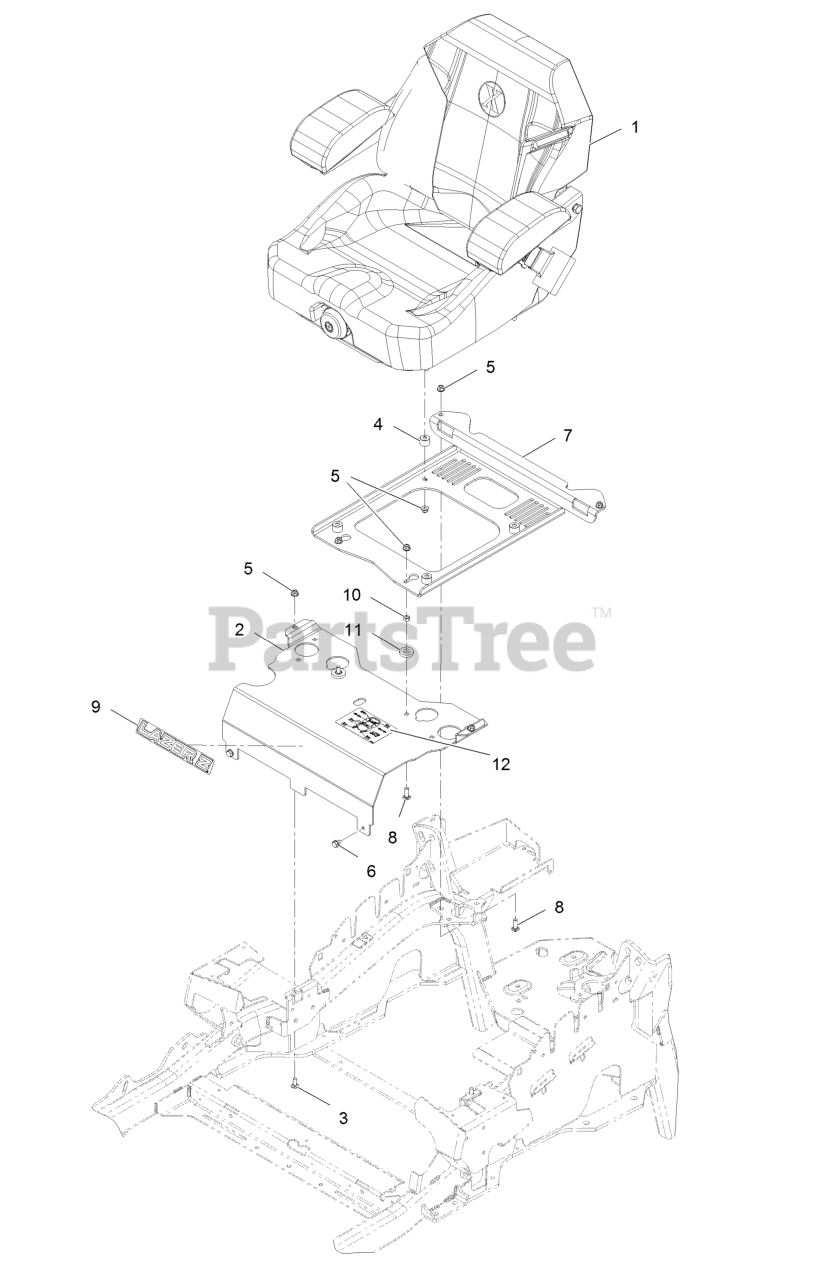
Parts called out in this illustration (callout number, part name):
1	Kit-Suspension Seat
2	Panel-Front, Seat Mount
3	Bolt-Carriage 5/16-18 X 3/4 Short Neck
5	Nut-Nyloc 5/16-18 Flg
6	Screw-HWH 5/16 X 1/2 Tf
7	Plate-Support, Seat
8	Bolt-Carriage 5/16-18 X 1 Sp
9	Decal, Lazer Model
10	Nut-Hex 5/16-18
11	Spacer-Blade Drive
12	Decal-Service Aid
